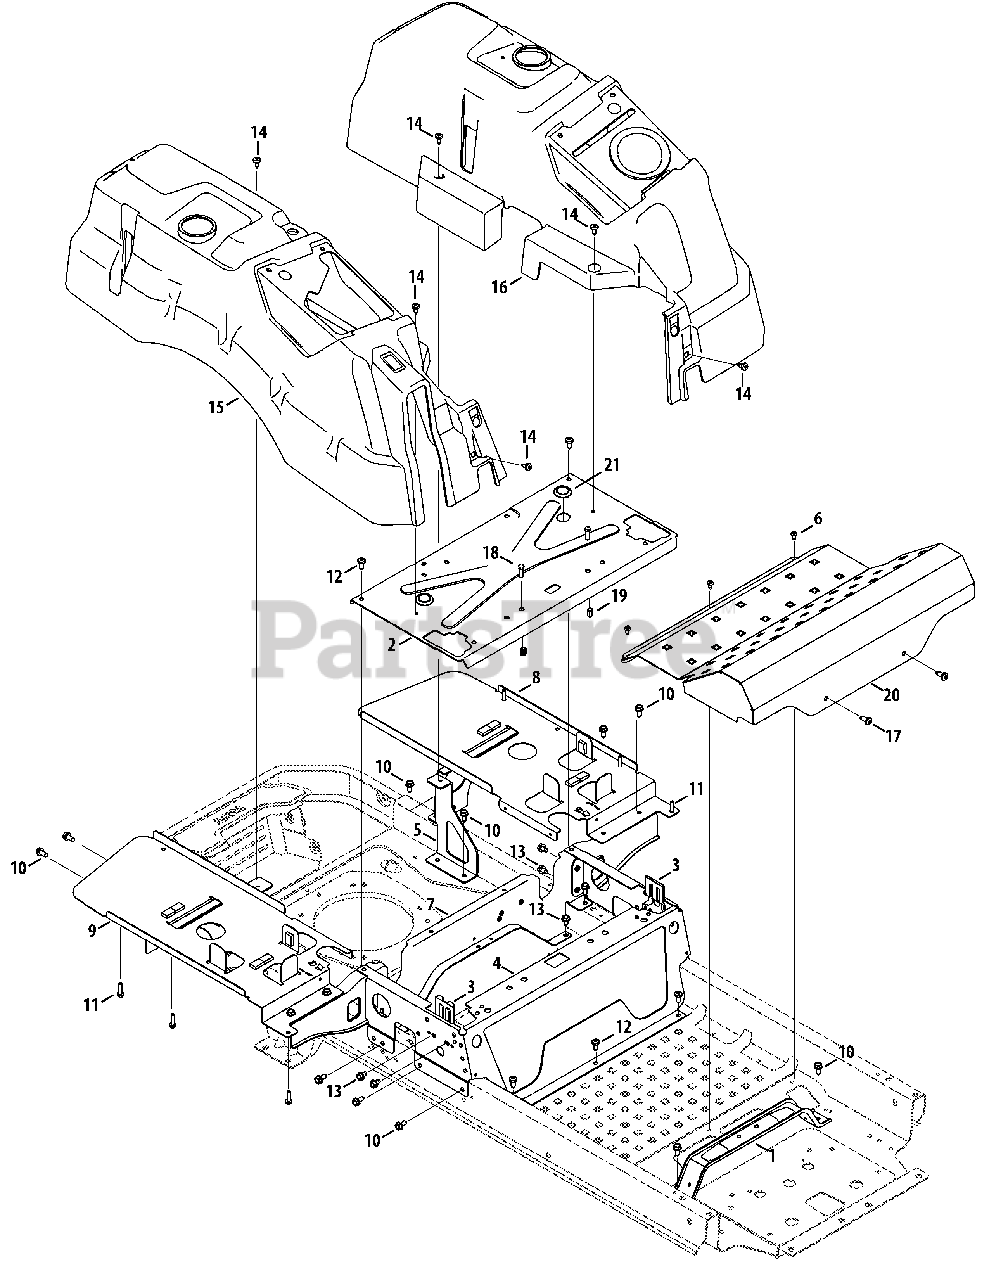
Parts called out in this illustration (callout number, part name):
1	Steering Support Bracket
2	Seatbox Plate
3	Lapbar Brace Bracket
4	Seat Frame
5	Rear Support Bracket, LH
5	Rear Support Bracket, RH
6	Screw, 1/4-20 x .50
7	Rear Seatbox Brace
8	Tank Support Plate, LH
9	Tank Support Plate, RH
10	Hex Washer Screw, 5/16-18 x .750
11	Hex Washer Screw, 5/16-14 x 1.00
12	Self Tapping Screw, 5/16-18 x .750
13	Hex Washer Screw, 5/16-18 x .50
14	Shoulder Screw, 1/4-20
15	RH Console
16	LH Console
17	Screw, 5/16-18 x .75
18	Hex Cap Screw, 5/16-18 x 1.00
19	Nut, 5/16-18
20	Floor Board, Fab
21	Button Plug
